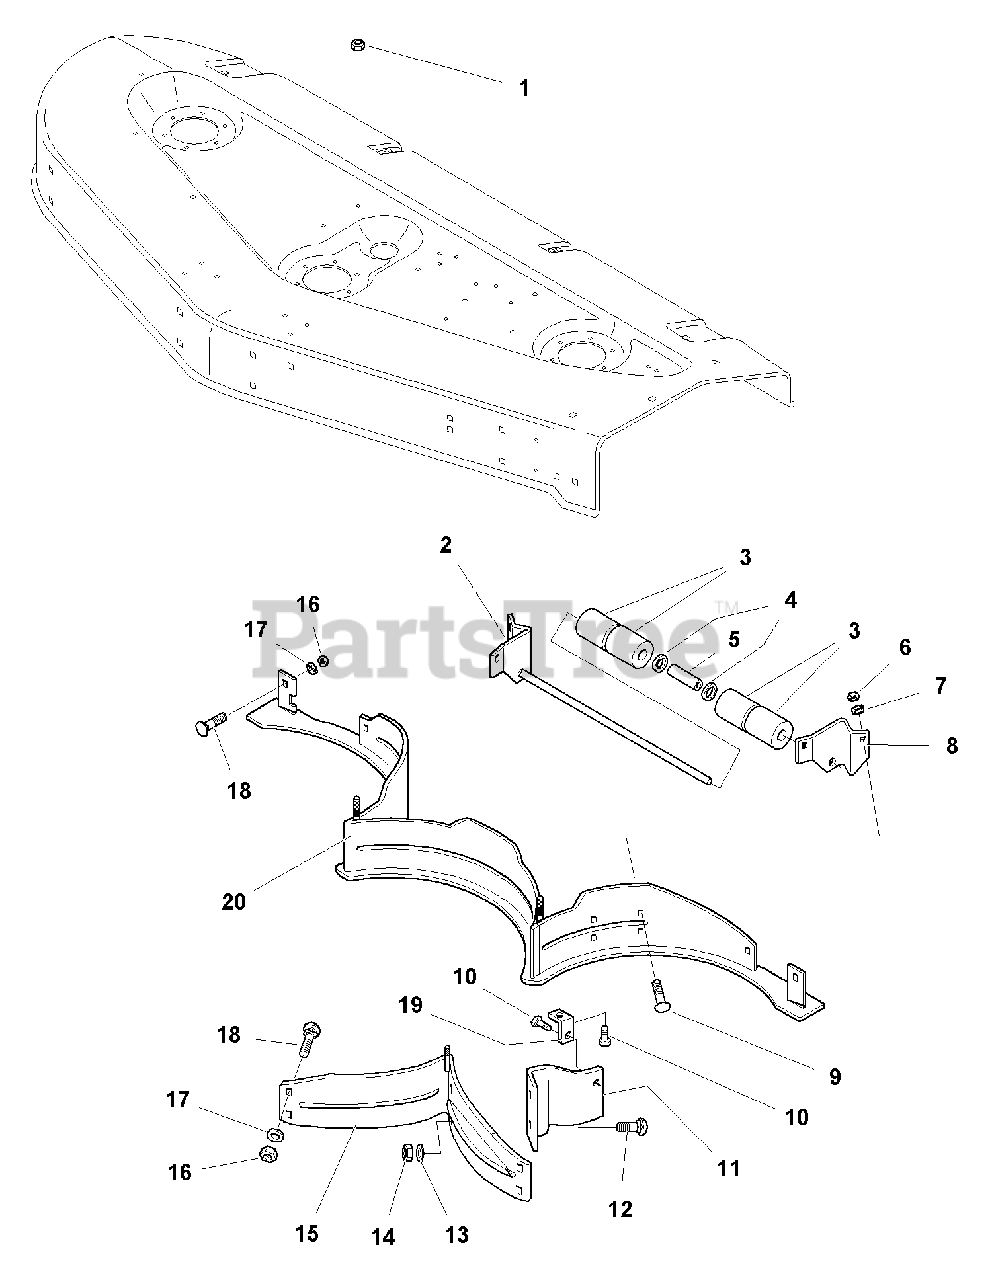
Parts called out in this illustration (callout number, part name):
1	NUT, Hex Centerlock, 5/16-18
2	BRACKET & SHAFT ASSEMBLY, Inner
3	ROLLER ASSEMBLY
6	NUT, Hex, 5/16
7	LOCKWASHER, 5/16
8	BRACKET, Inner, LH
9	CARRIAGE BOLT, 5/16-18 x 3/4
10	CAPSCREW, Taptite, 5/16-18 x 5/16
11	BAFFLE, Discharge
12	CARRIAGE BOLT, 5/16-18 x 3/4
13	LOCKWASHER, 5/16
14	NUT, Hex,5/16-18
15	BAFFLE ASSEMBLY, Front
16	NUT, Hex, 3/8-16
17	LOCKWASHER, 3/8
18	CARRIAGE BOLT, 3/8-16 x 1
19	BRACKET, Mower
20	BAFFLE ASSEMBLY
